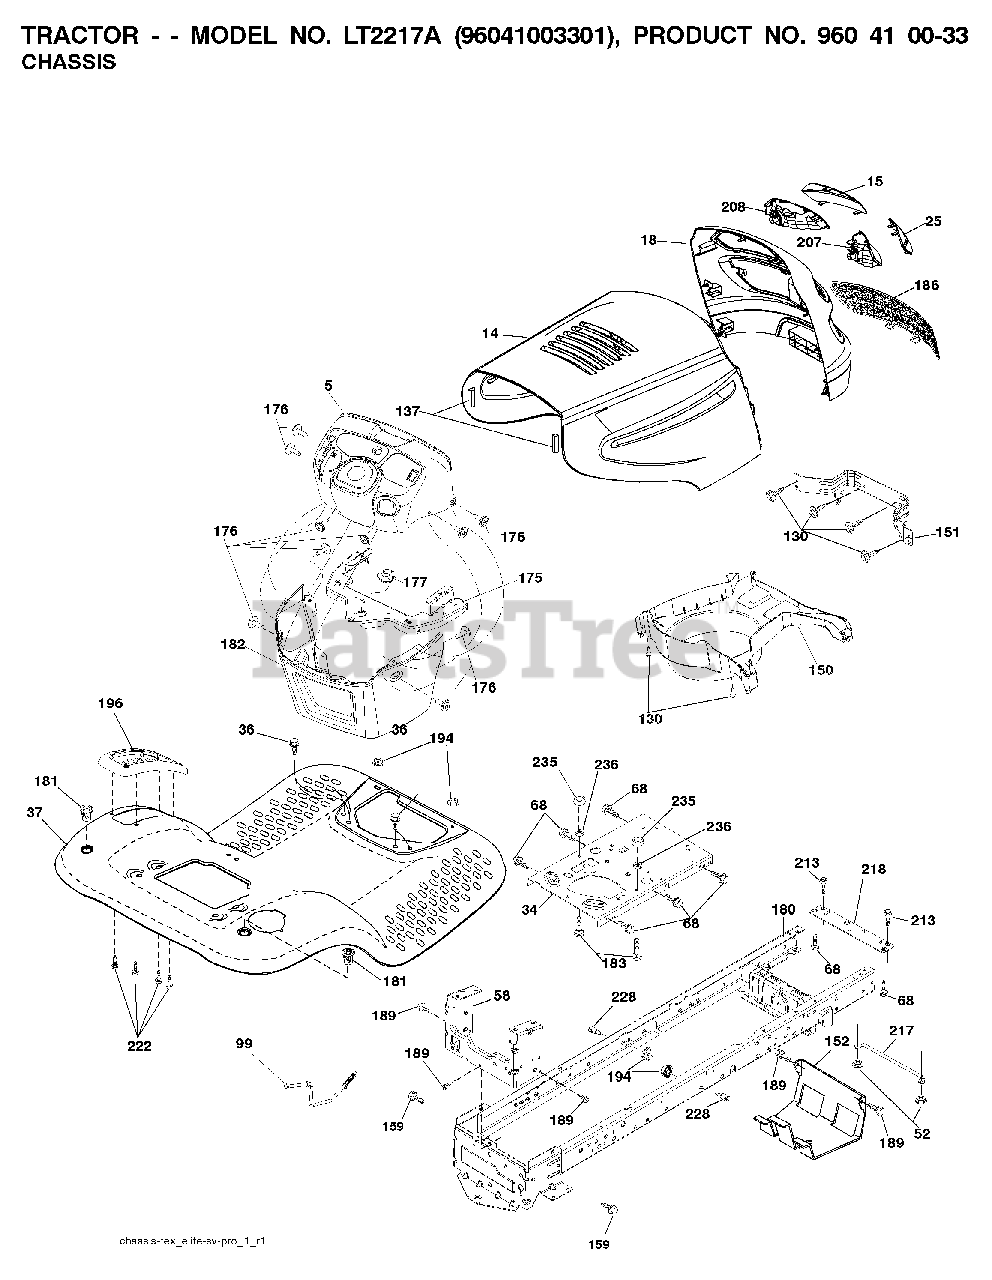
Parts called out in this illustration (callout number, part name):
34	PLATE.ENGINE.WELDED.CHASSIS
36	SCREW 5/16"
52	LOCKNUT
58	DRAWBAR UPPER 2PC SMALL FENDER
99	ROD ASM BYPASS
130	SCREW
137	BUMPER.HOOD.LARGE.1.75"
151	BRACKET PIVOT
152	SHIELD BROWNING
159	SCREW, 3/8-16X3/4
175	CROSSMEMBER.LT
176	SCREW.#10-24X5/8.RN.QU
177	BUSHING STEERING
181	FEND/FTRST.PCH.CPH.NFW
182	DASH.LOWER.LT.CCS
183	BOLT.5/16-18X1-1/4 FULL.THREAD
189	SCREW
194	NUT LOCK HEX FLANGE 5/16-18
196	CONSOLE.ASM.DECK.LIFT.TLT.BLAC
207	BEZEL GRILL RH
208	BEZEL GRILL LH
213	BOLT
217	ROD.PIVOT.HOOD
218	X-PIECE.HOOD.STOP.NON/
222	SCREW.1/4-20X5/8
228	STUD.FASTNER.W/ANTI-ROTATE
235	SPACER FENDER
236	NUT.CENTERLOCK.5/16-
288	WASHER
